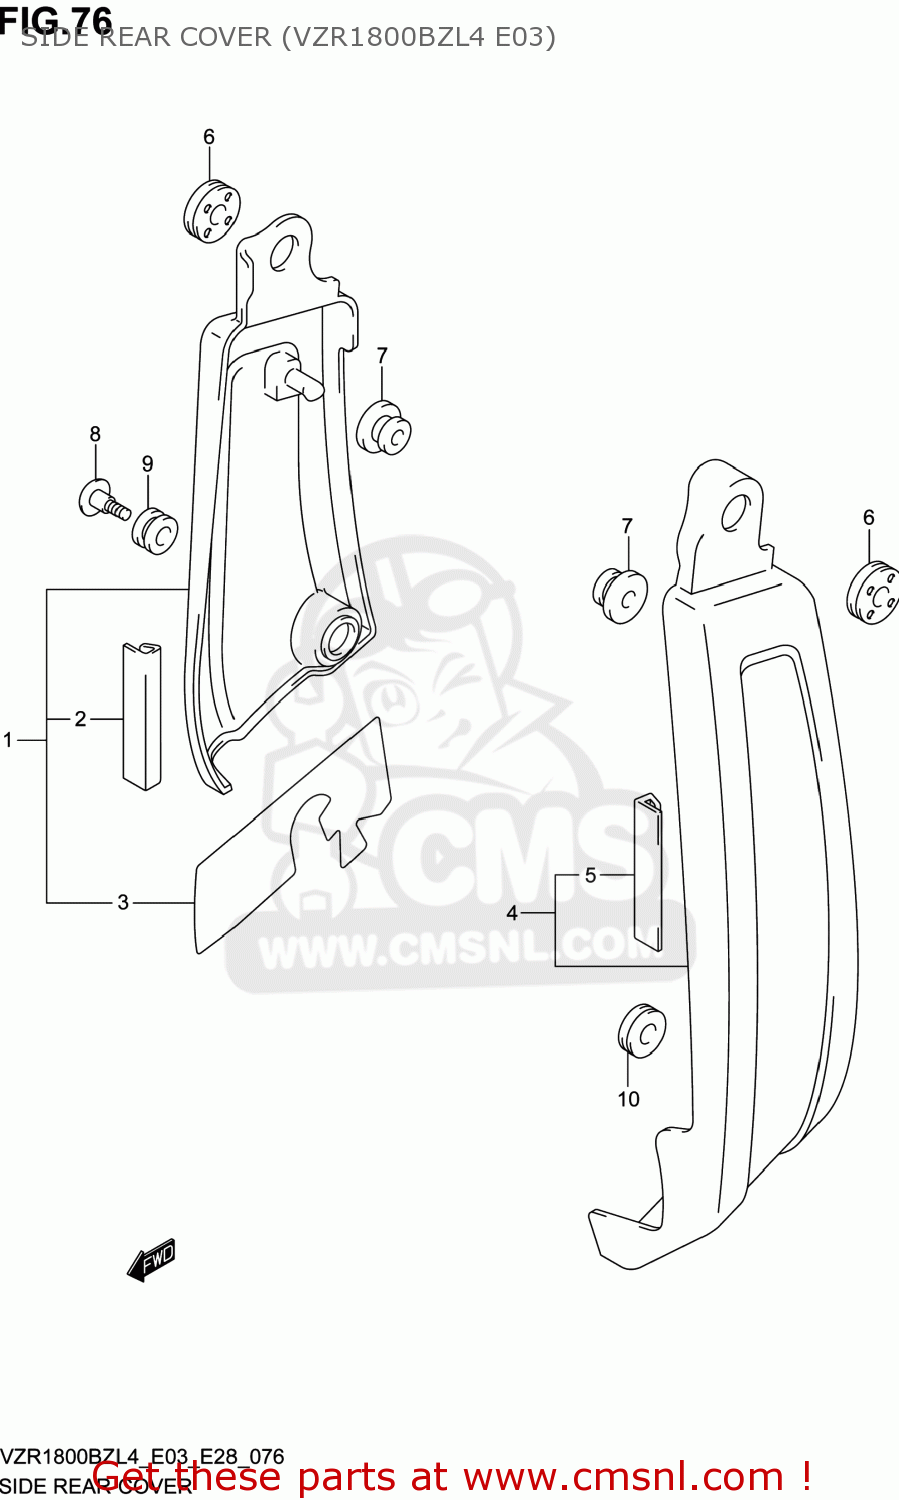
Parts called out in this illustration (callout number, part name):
1	COVER,SIDE REAR,R(BLACK)
2	MOLDING
3	SHIELD,SIDE REAR COVER,R
4	COVER,SIDE RR,L
5	MOLDING
6	CUSHION
7	CUSHION
8	SCREW(6X20)
9	CUSHION
10	CUSHION
